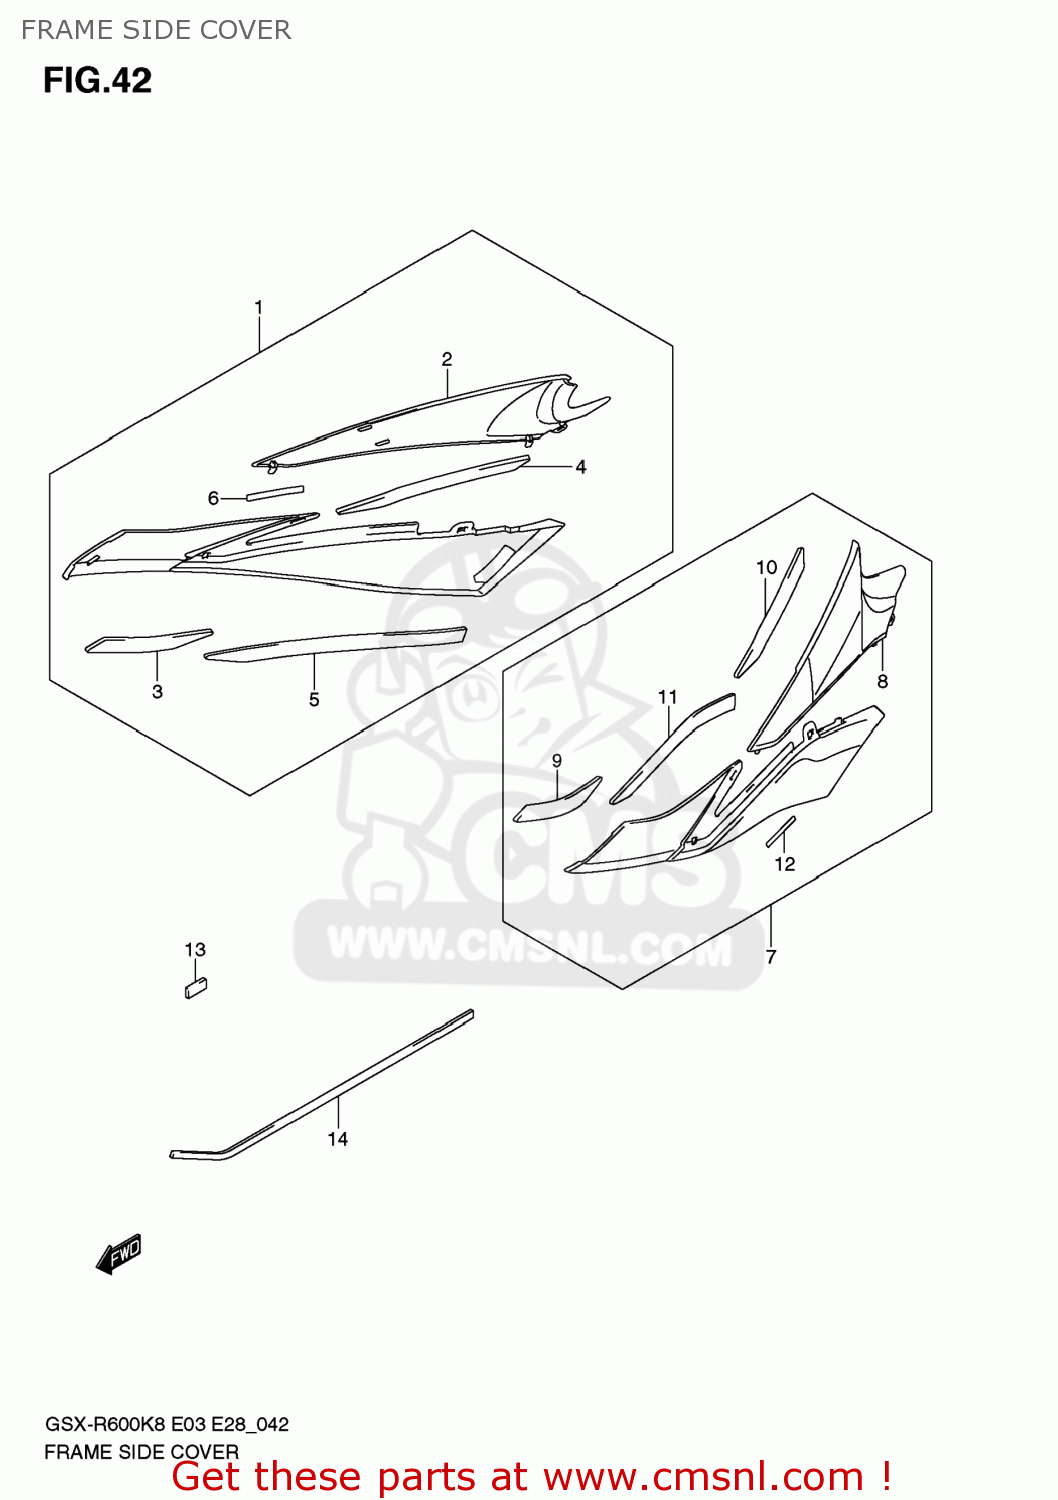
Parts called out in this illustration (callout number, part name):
1	COVER,FRAME SIDE,R(BLACK)
2	COVER,UPR,R
3	CUSHION,FRAME COVER FR,R
4	CUSHION,FRAME COVER UPR,R
5	CUSHION,FRAME COVER LWR,R
6	CUSHION,CTR
7	COVER,FRAME SIDE,L(BLACK)
8	COVER,UPR,L
9	CUSHION,FRAME COVER FR,L
10	CUSHION,FRAME COVER UPR,L
11	CUSHION,FRAME COVER LWR,L
12	CUSHION,CTR
13	CUSHION
14	CUSHION,SIDE COVER UPR
